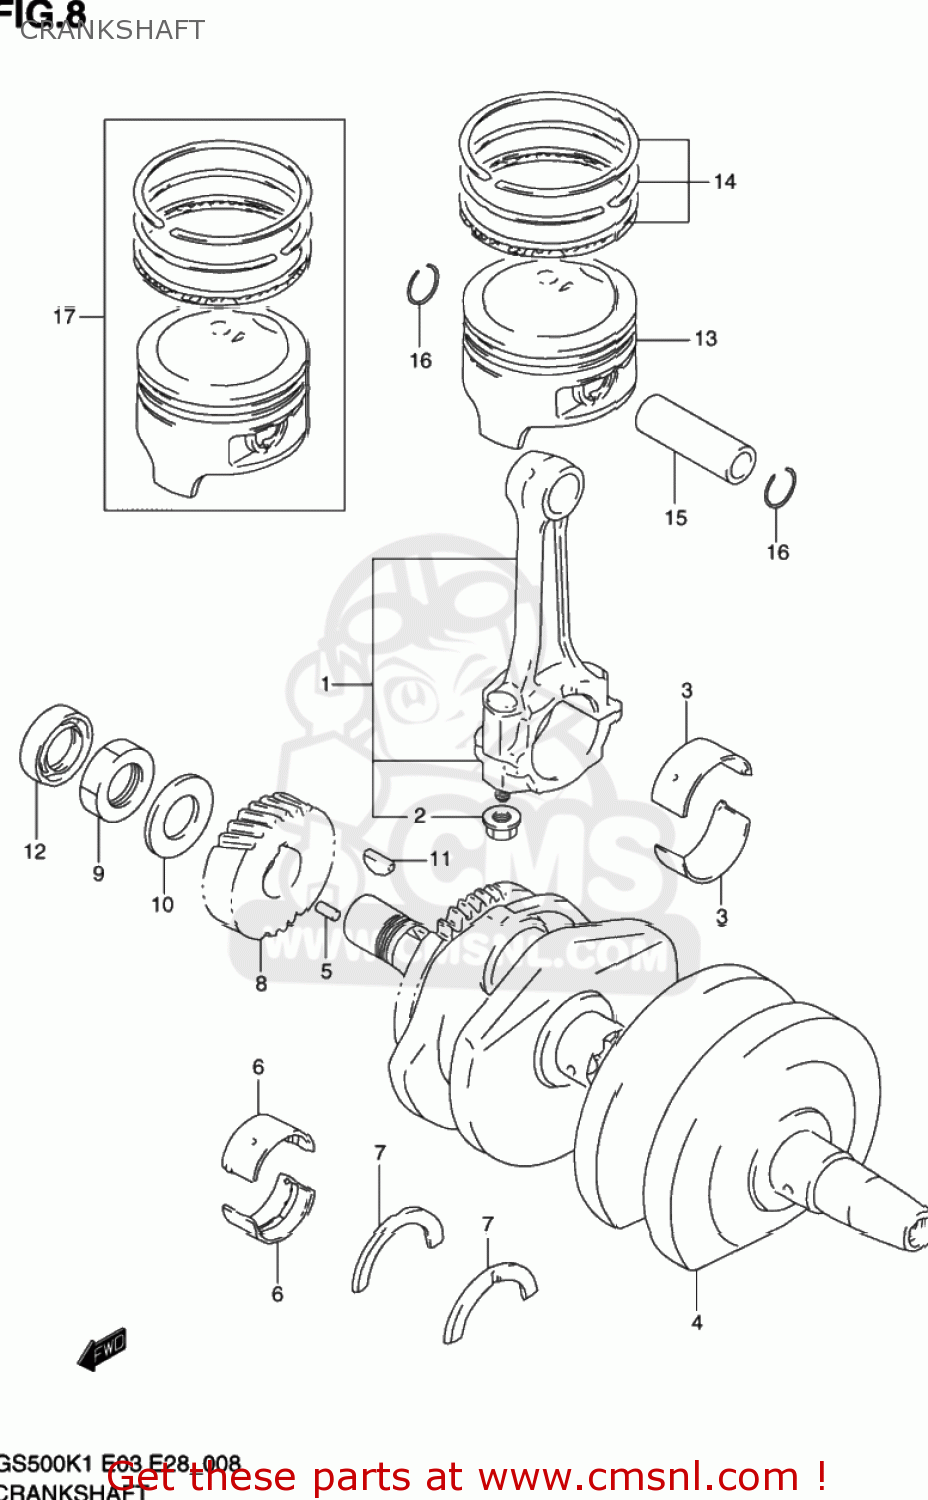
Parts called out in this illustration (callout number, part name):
1	ROD ASSEMBLY,CONNECTING
2	NUT
3	BEARING,CRANK PIN
4	CRANKSHAFT
5	PIN
6	BEARING,CRANKSHAFT(GREEN)
7	BEARING,CRANK THRUST
8	GEAR,PRIMARY DRIVE NO.28
9	NUT
10	WASHER
11	KEY
12	SEAL,OIL(22X40X8)
13	PISTON (74.00MM)
14	RING SET,PISTON
15	PIN,PISTON (18MM)
16	CIRCLIP
17	PISTON SET(OS:0.5)
